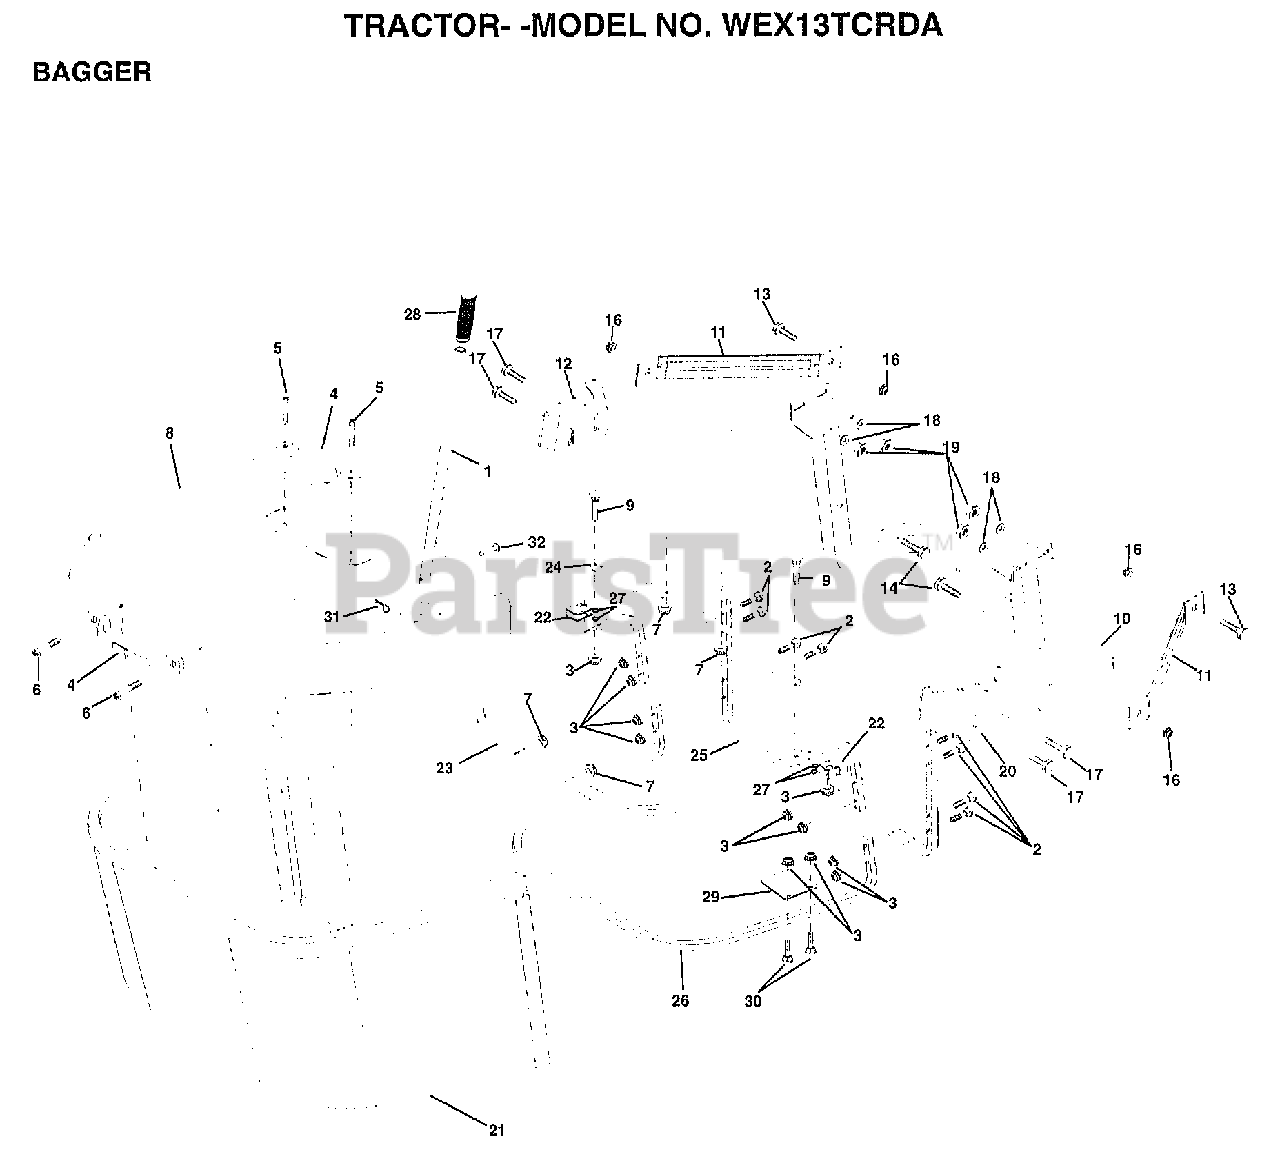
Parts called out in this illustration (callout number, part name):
1	TUBE.HDLE.BAG.CRD
2	BOLT.CARRIAGE.1/4-20X2.0
4	HANDLE.GRAB.BLACK.
5	"SCREW,PAN.HEAD"
7	NUT.WIZ.LOCK
8	COVER.BAGGER.CRD
9	BOLT CARRIAGE
10	SUPT.ASM.WLDMNT.BAG.CRD
11	BRKT.SUPT.UPPER.BAG.CRD
12	BRKT.PIVOT.BAG.LH.CRD
13	BOLT
14	BOLT.HEX.3/8-16X2-1/2
17	BOLT
18	WASHER
19	NUT
20	"BRKT.PIVOT.BAG,RH.CRD"
21	BAG.ASM.CRD
22	BRKT.SIDE.BAG.CRD
23	TUBE.UPPER.BAG.CRD
24	TUBE.PIVOT.BAG.CRD
25	TUBE.FT.BAG.CRD
26	TUBE.LOWER.BAG.CRD.
27	GROMMET.EXTRUDED
28	GRIP.HANDLE.BLACK
29	PLATE.STOP.BAG.HDLE.CRD
30	BOLT.CARRIAGE
31	RETAINER M
32	RIVET.DRILL.1.75
